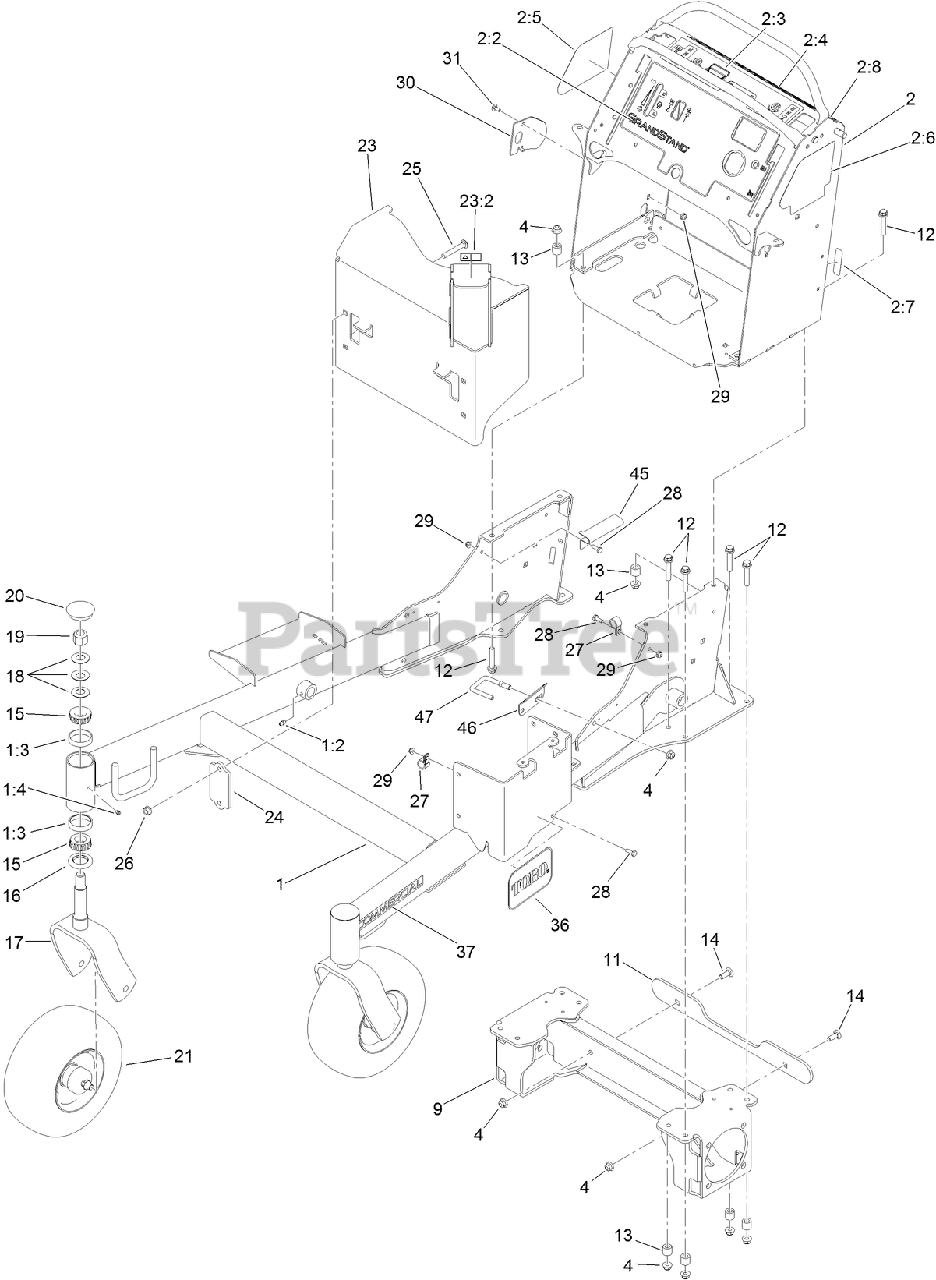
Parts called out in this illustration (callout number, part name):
1	FRONT FRAME ASM
1:2	FITTING-GREASE
1:3	CUP-BEARING
2	CONTROL TOWER ASM
2:2	DECAL-PANEL, CONTROL
2:3	DECAL-OPC
2:4	DECAL-WARNING
2:5	DECAL-HOC
2:6	DECAL-SERVICE AID, CE
2:7	DECAL-FUSE
2:8	DECAL-STABILITY, CE
4	NUT-HF, NI
9	FRAME-MOTOR
11	PLATE-SPACER, BUMPER
12	SCREW-HHF
13	SPACER
14	SCREW-CARR
15	BEARING-ROLLER, TAPERED
16	SEAL-GREASE
17	FORK-CASTER
18	WASHER-BELLVILLE
19	NUT-LOCK, NI
20	CAP-GREASE
21	WHEEL/TIRE AND BEARING ASM
23	MUFFLER GUARD ASM
23:2	DECAL-WARNING
24	BRACKET-MOUNTING, GUARD
25	SCREW-CARR
26	NUT-HF
27	CLAMP-CABLE
28	SCREW-HH
29	NUT-HF
30	PLATE-STRIKER
31	SCREW-CARR
36	DECAL
37	DECAL-COMMERCIAL
45	BRACKET-HOSE, FUEL (DOUBLE)
46	GUARD-HOSE
47	GUIDE-HOSE
